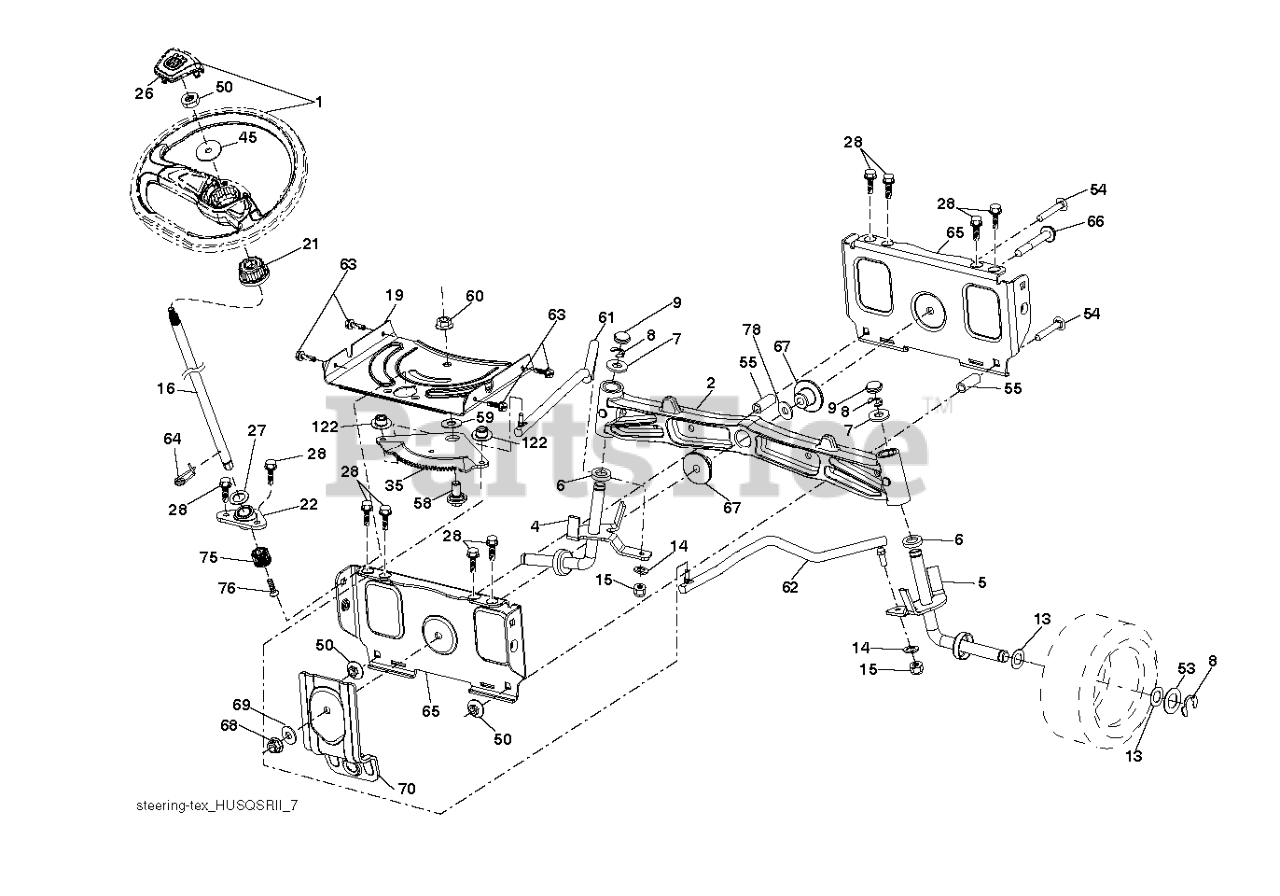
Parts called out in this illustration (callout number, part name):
1	Service Kit
2	AXLE.CAST.IRON
4	SPINDLE.WELDED.LH.16"TEX
5	SPINDLE.WELDED.RH.16"TEX
6	WASHER THRUST
9	CAP.SPINDLE.BLACK
15	NUT CROWNLOCK 3/8-24
16	SHAFT.STEER.2HIGH.SPLND.PLATED
19	PLATE.STEER.DDL.NLT/NG
21	ADAPTER.WHEEL.STEER.SPLND.ALUM
22	BEARING.SHAFT.STEER.LOWER.625
28	SCREW, 3/8-16X3/4
35	GEAR.SECTOR.PLATE.DDL.
45	WASHER.3/8ID.2-3/8OD.12GA.PLTD
50	NUT LOCK FLG 3/8-16 UNC
53	WASHER.HARDENED
55	SPACER.BRACE.AXLE
58	BOLT.SHOULDER.SECTOR.P
59	WASHER.THURST.SECTOR.S
60	NUT FLANGE LOCK 5/8-11
63	SCREW
64	RETAINER.CLIP.SPRING.S
65	BRACE.AXLE.FRONT.NLT/N
66	BOLT HEX FGHD 7/16-14 X 3 SERR
67	BUSHING.PM.FRONT AXLE
68	NUT.LOCK.FLANGE.7/16
69	WASHER.1.5X.505X.118
70	BRACKET.FRT.DECK.SUSP.RR.MT431
75	PINION.ZINC PLATED
76	SCREW HEAD SOCKET LRVB
78	THRUST WASHER
122	CAP.GEAR.SECTOR.TEX
